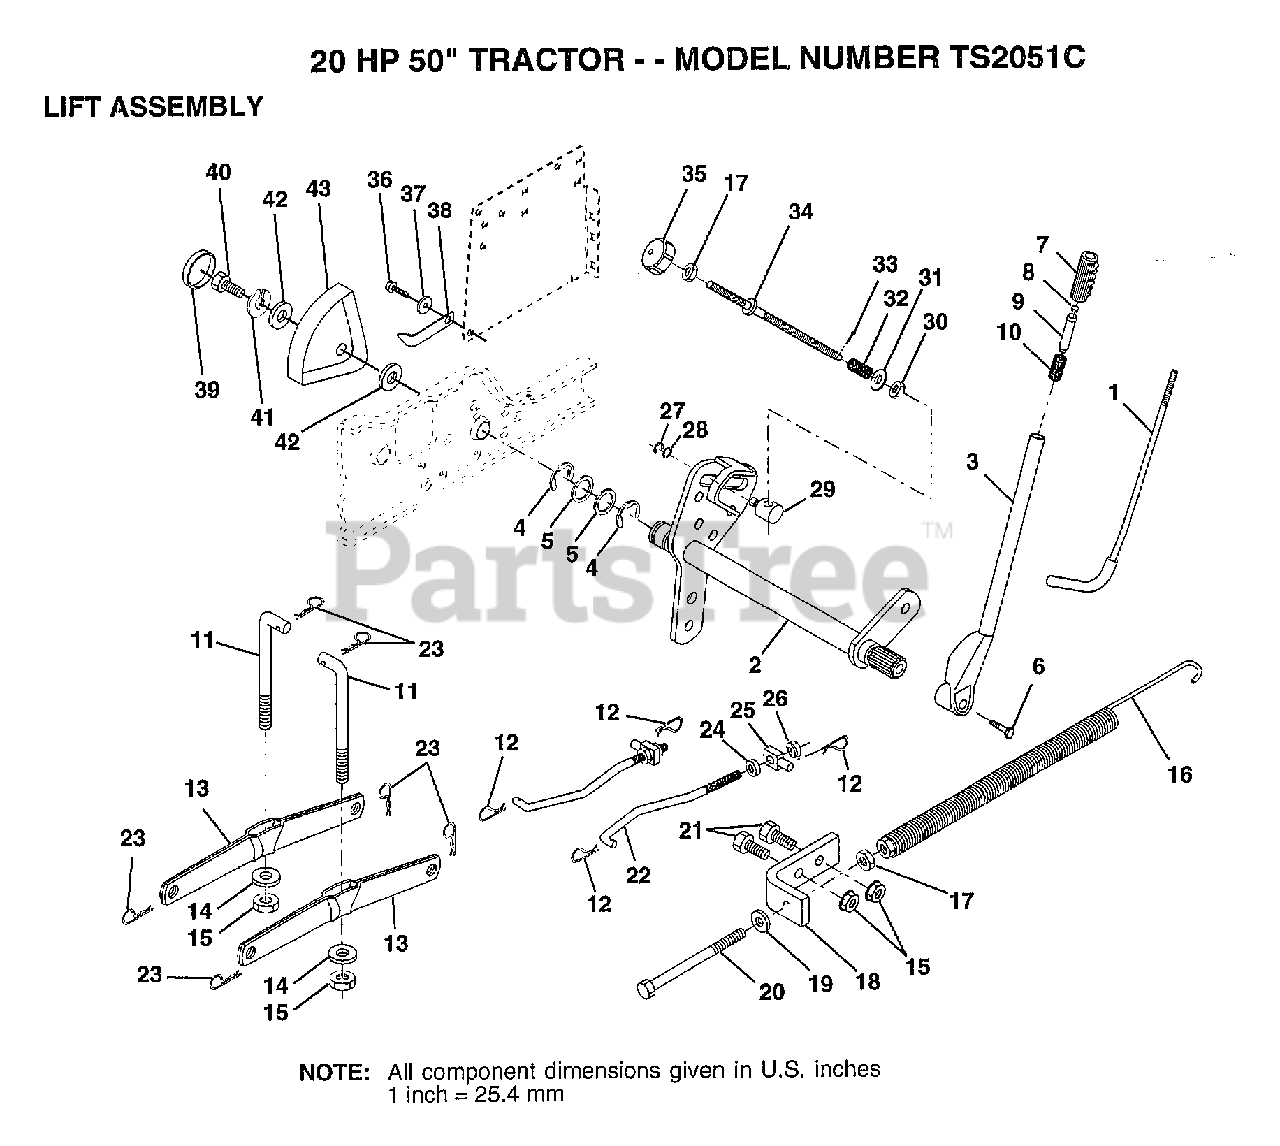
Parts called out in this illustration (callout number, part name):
1	LEVER ROD LT
4	E-RING
5	WASHER
6	"BOLT,HEX"
7	GRIP HANDLE
10	SPRING T
12	RETAINER.SPRING
14	BEARING PVT LH
15	NUT
17	NUT
18	BRACKET SPRING AS
19	WASHER
20	BOLT-ADJ SPRING T
21	BOLT
22	LINK.FRONT
24	NUT
25	TRUNION
26	NUT.LK.W/WSH.1/2.
27	KLIP RING
28	WASHER
29	TRUNION LT
30	NUT T
31	WASHER
32	SPRING.COMP.INF.H
34	ROD.ADJ.LIFT
35	KNOB INF 3/8-16
36	SCREW
37	WASHER T
38	POINTER HGT IND
39	"PLUG,HOLE"
40	SCREW
41	LOCKWASHER
42	WASHER
43	HEIGHT INDICATOR
